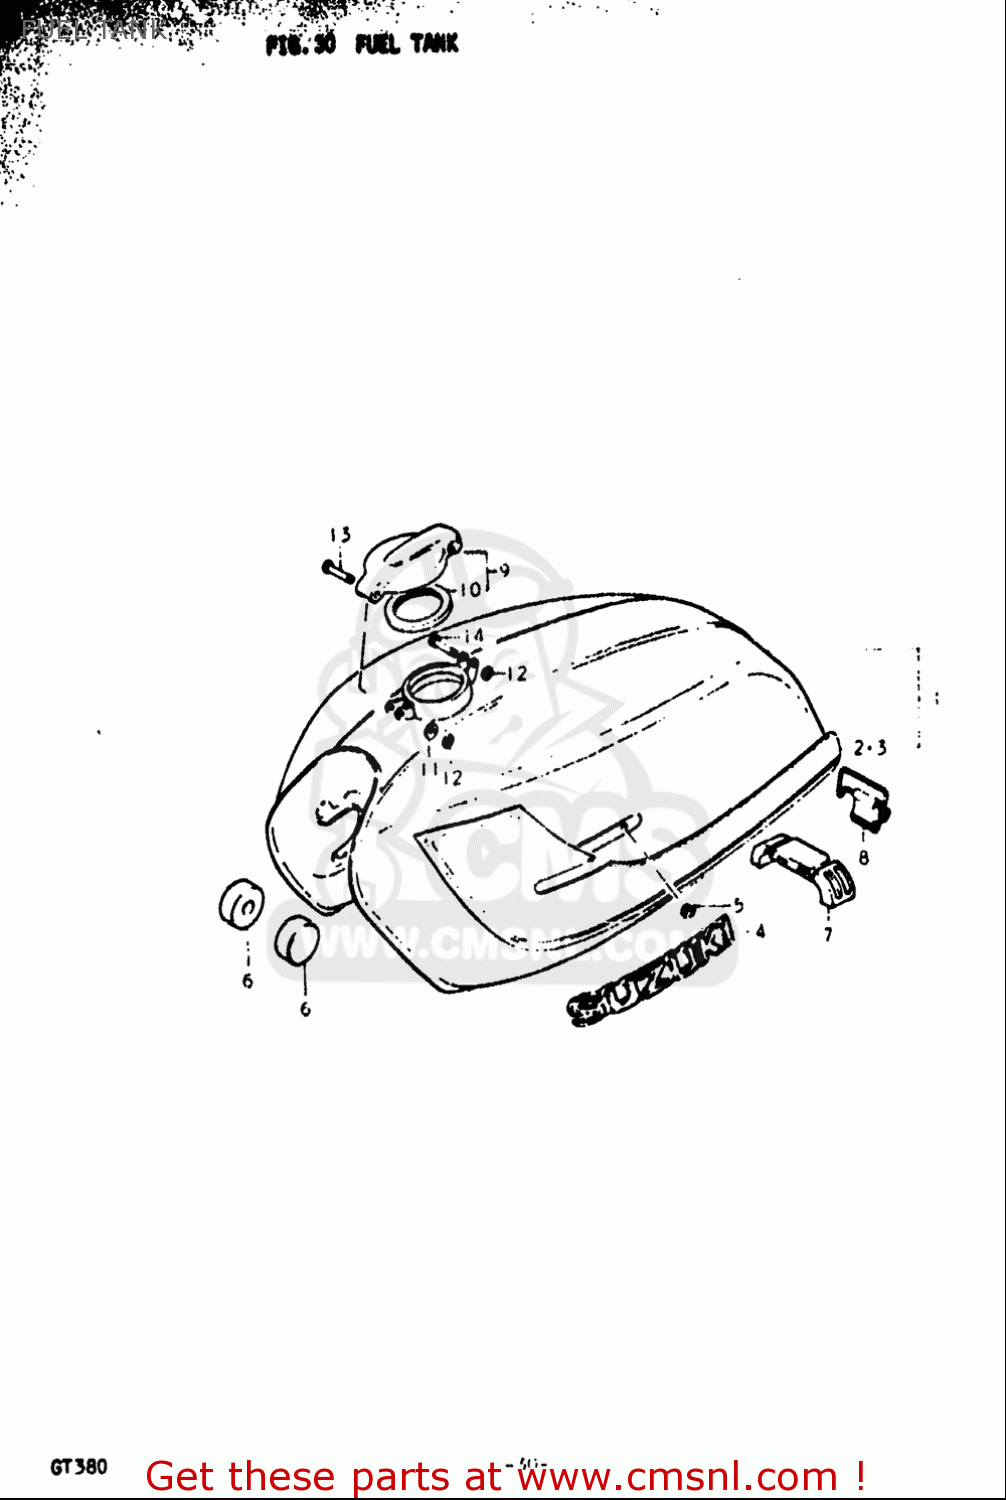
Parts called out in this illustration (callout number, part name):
5	NUT
6	CUSHION
7	CUSHION
8	BAND
9	CAP ASSY,FUEL TANK
11	WASHER
12	E RING
